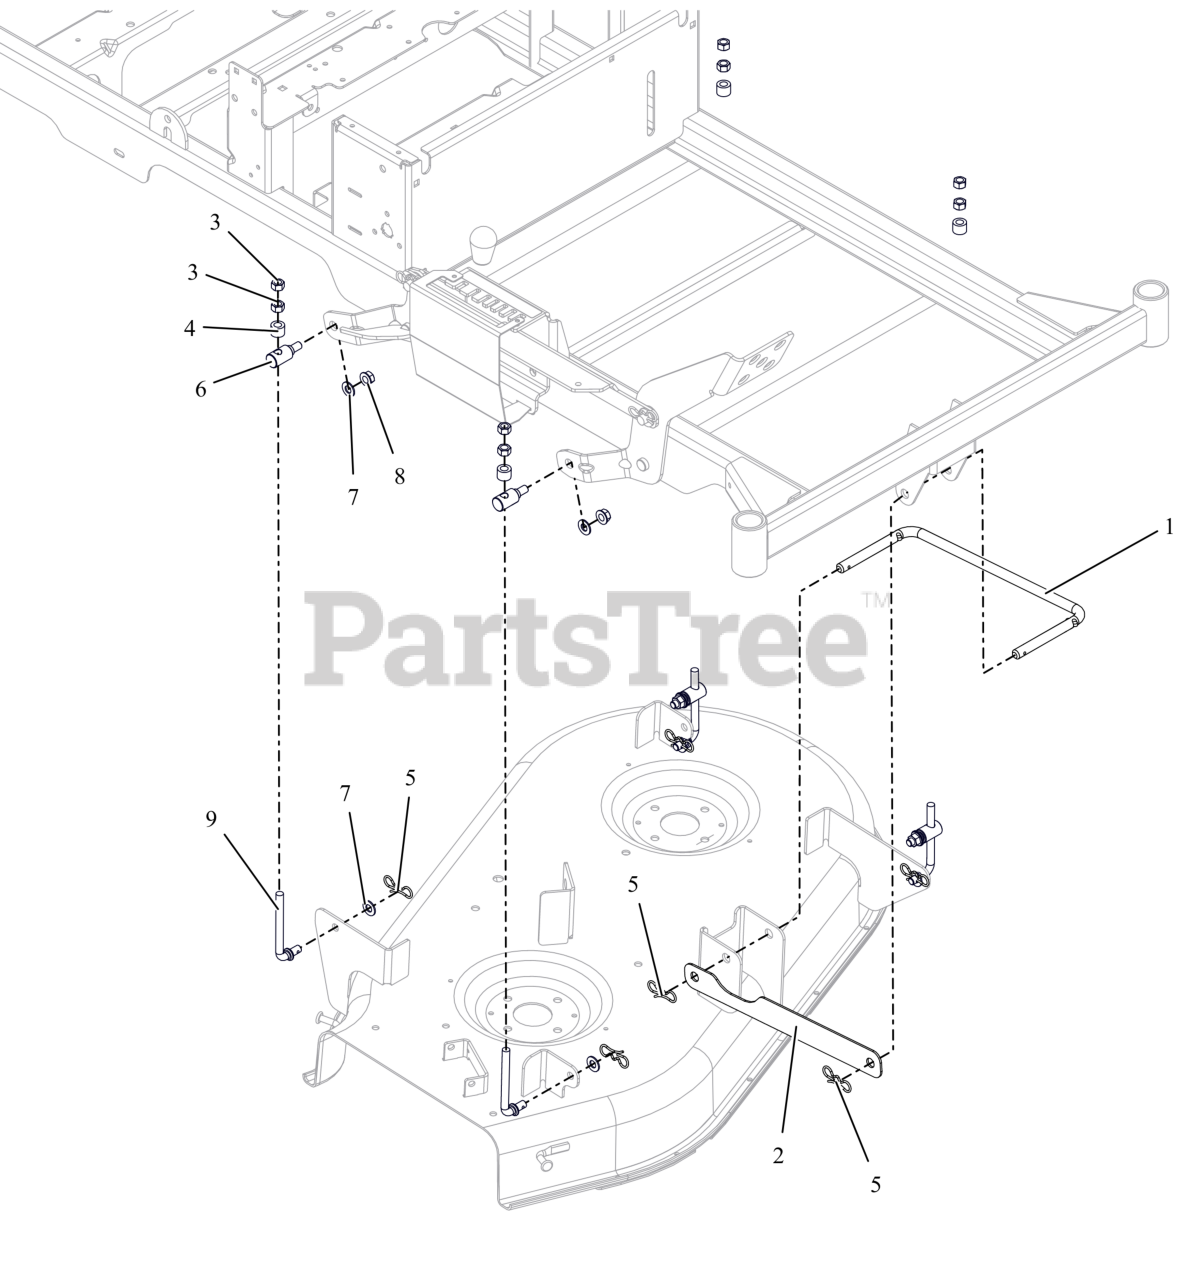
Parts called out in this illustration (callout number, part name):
1	WIREFORM, DRAG LINK
2	STRAP, DRAG LINK (ORANGE)
3	NUT-STD .375-16 G2 ZCC
4	BSHG-SLV .391X.688X.52 PM
5	PIN, BOWTIE .091X1.875 ZCC
6	TRUNNION, DECK ADJUSTER
7	WSHR,FLT .406X.812X.065 ZCC
8	NUT-LK-CTR-FLG .375-16 GF ZCC
9	WIREFORM, DECK ADJUSTMENT
